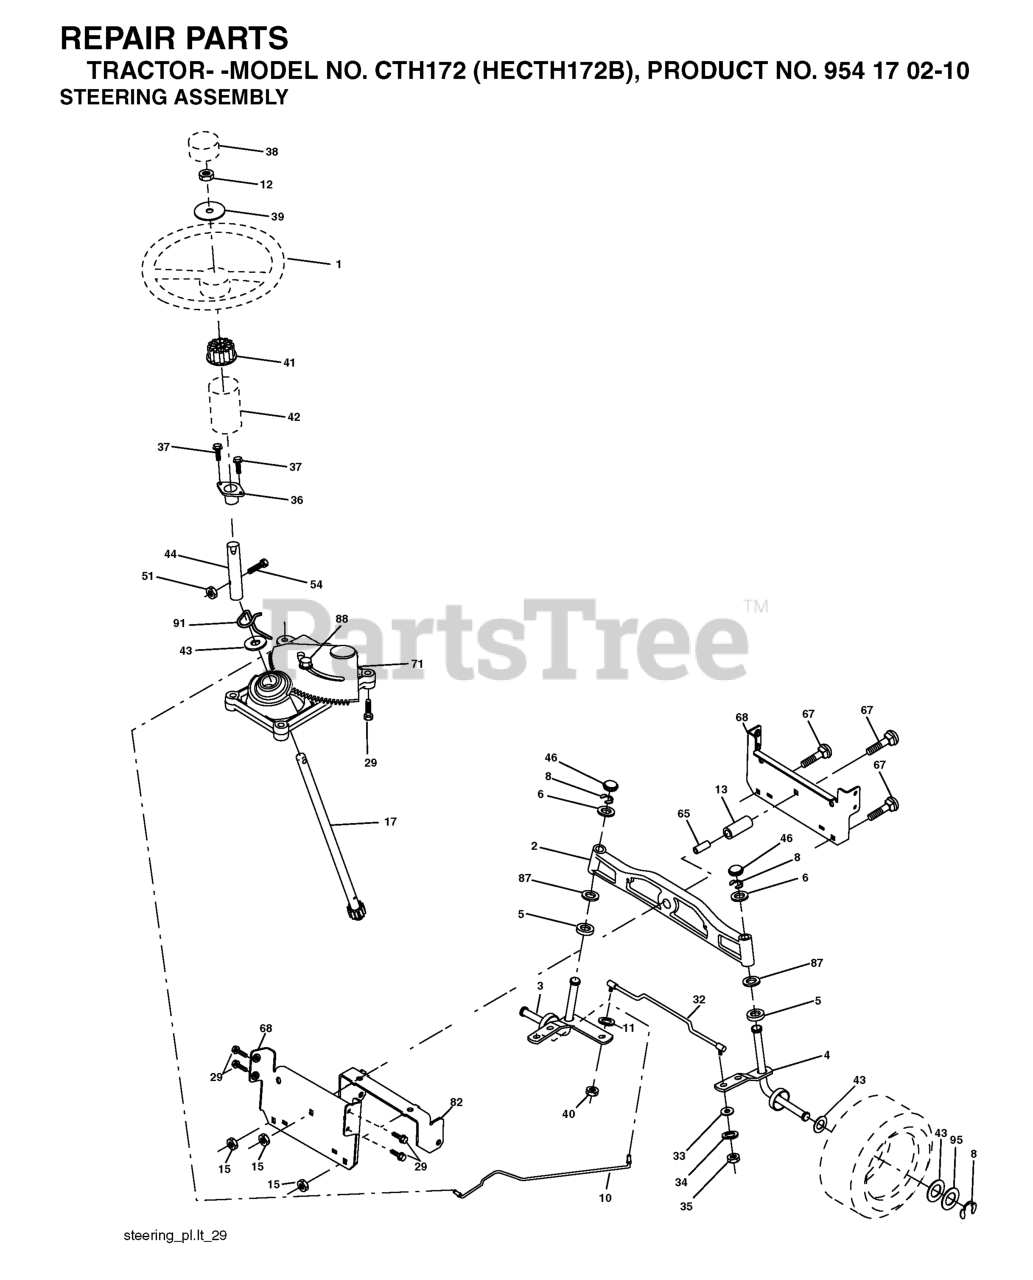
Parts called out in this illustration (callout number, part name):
1	STEERING WHEEL
2	AXLE ASSY FRONT
3	SPINDLE.ASM.LH.15"TIRES
4	SPINDLE.ASM.RH.15"TIRES
5	THRUST WASHER
10	DRAGLINK.15".TIRES.2001
11	WASHER, LOCK 3/8
12	NUT.HEX.1/2-20
13	TUBE, PIVOT AXLE
15	NUT
17	SHAFT ASM, STEERING
29	SCREW, 3/8-16X3/4
32	ROD.ASM.TIE.BALL.JOINT.NOVAN
33	WASHER M
34	WASHER.LOCK.HVY.HLCL.SPR.5/16
35	NUT, CROWNLOCK
36	BUSHING, STEERING
37	SCREW.TT.#10-32X.5.3/8.FLANGE
38	CAP.WHEEL.STEERING.GREY
39	Washer 9/16 ID x 1 1/2 OD 11 Ga. Zin
40	NUT CROWNLOCK 3/8-24
41	STEERING WHEEL ADAPTOR
42	BOOT STEERING
44	EXT, STEERING SHAFT
46	CAP.SPINDLE.BLACK
51	NUT.CROWNLOCK.1/4-28
54	Bolt Hex 1/4-28 unf x 1-1/4 Gr. 8
65	SPACER BRACE AXLE
67	BOLT CARRIAGE
68	BRACE.AXLE.15"TIRES
71	STEERING ASM
82	BRACKET
87	WASHER, FLAT .781 X 1 1/2"
88	BOLT, SHOULDER 7/16-20
91	CLIP.STEERING
95	WASHER.HARDENED
